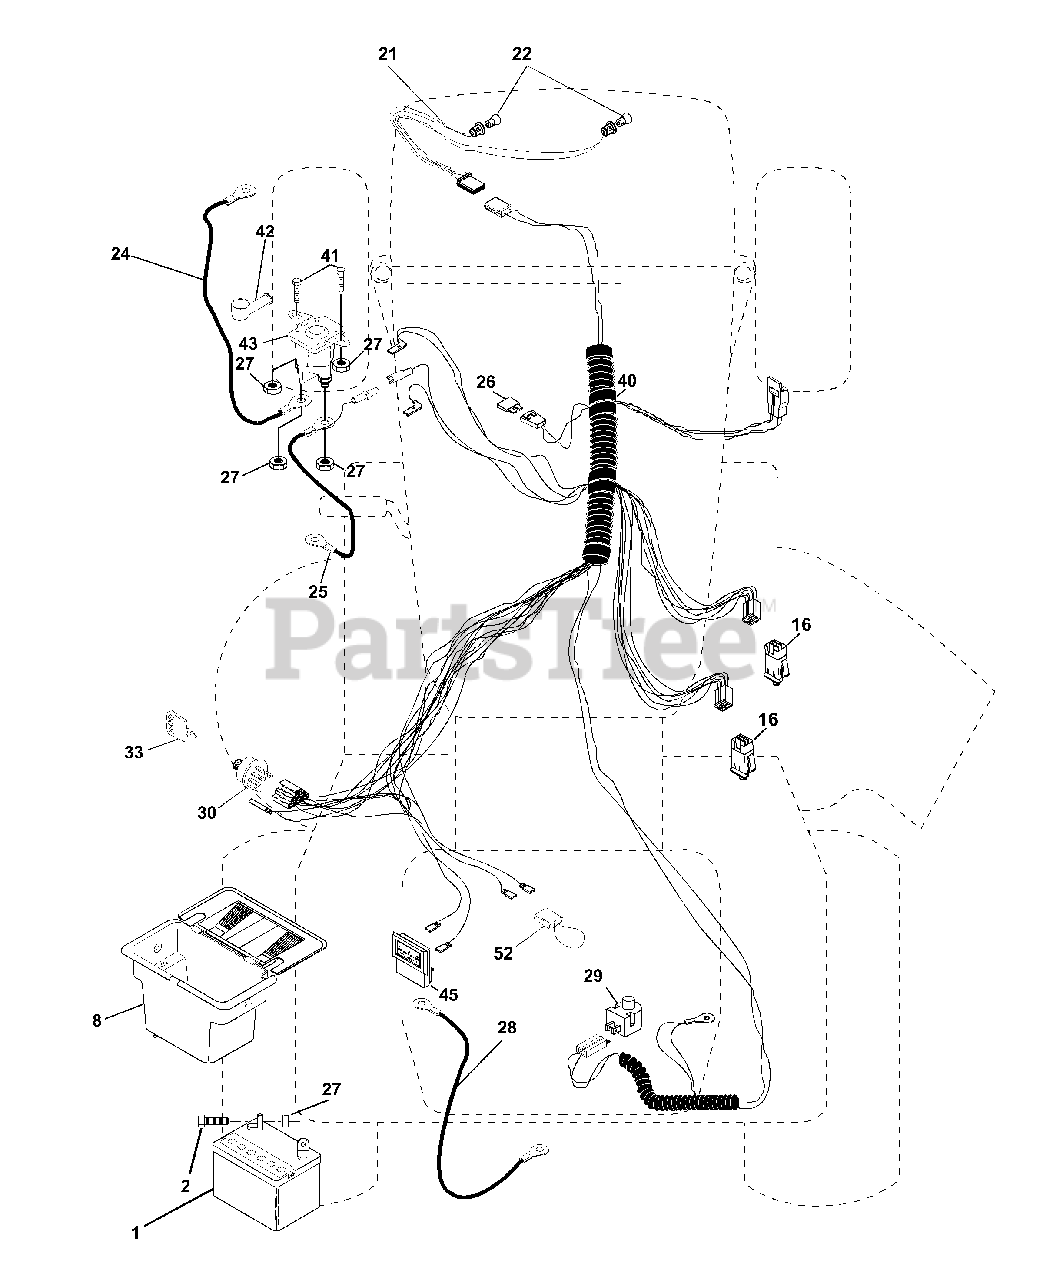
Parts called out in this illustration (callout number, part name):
1	Battery
2	Bolt Hex Hd 1/4-20unc X 3/4
8	Case Battery Mech Hinge
16	Switch Interlock Push-In
21	Harness Socket Light
22	Bulb, Light # 1156
24	Cable Battery
25	Cable Battery 6 Ga Red w/16 wire
26	Fuse 20 Amp
27	Nut Keps Hex 1/4-20 Unc
28	Cable Ground 6ga 12 black
29	Switch Plunger Nc Gray
30	Switch Ign
33	Key Ign Molded Generic
40	Harness Ign
41	Bolt Fin Hex 1/4-20uncx 1/2
42	Cover Terminal Red
45	Ammeter Rectangular
52	Protection Loop
